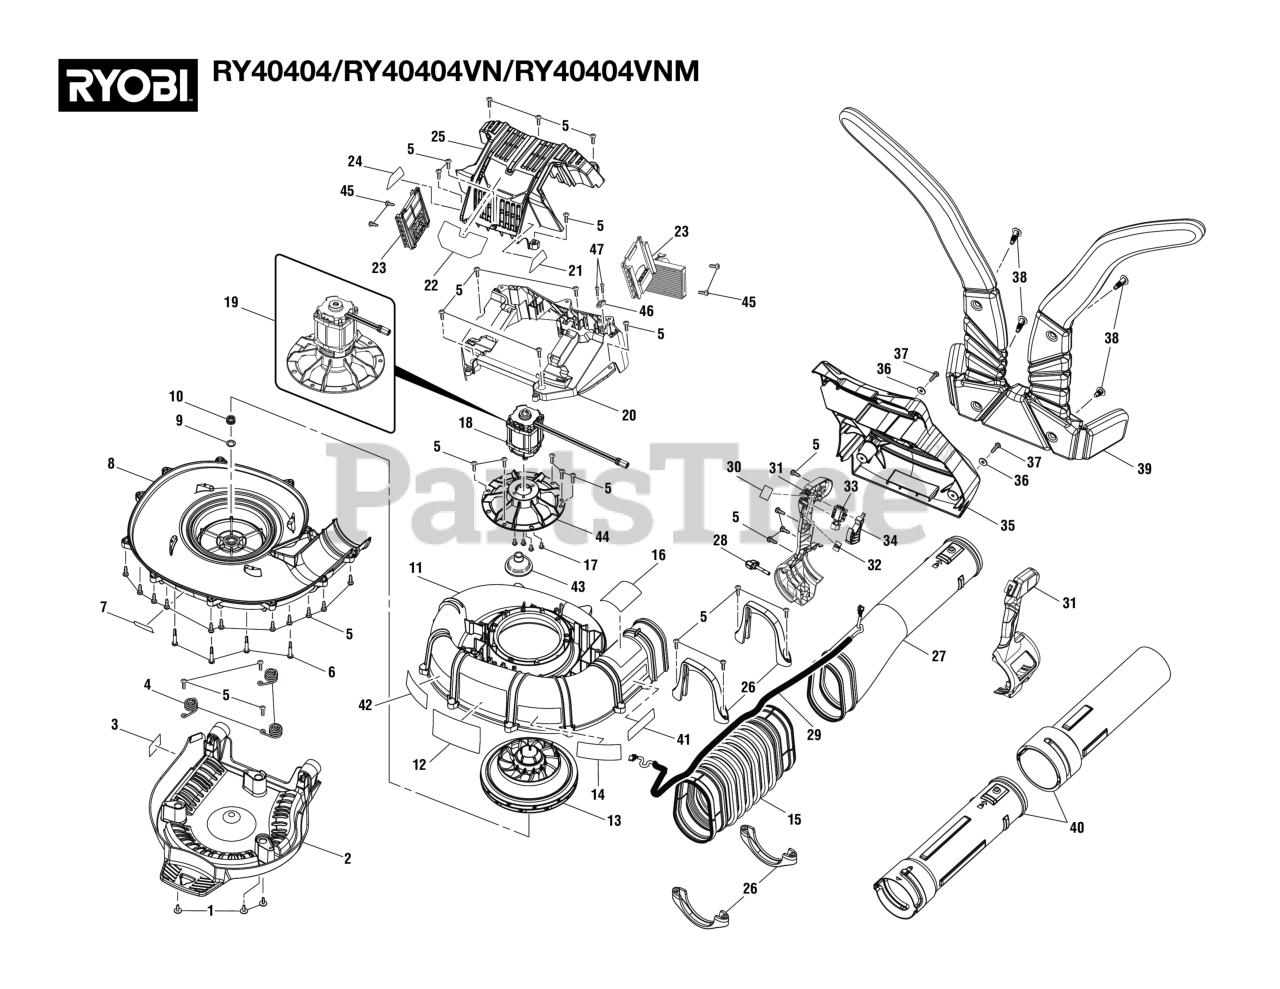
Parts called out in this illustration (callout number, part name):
1	Screw (10-14 x 16 mm)
2	Lower Frame Assembly
3	Data Label
5	Screw (10-14 x 19 mm, T25 Torx Truss Pan Hd. T.F.)
6	Shoulder Screw (M5 x 40 mm, T25 Torx Truss Hd. T.F.)
7	Hair Ingestion Warning Label
8	Outer Volute Assembly
9	Washer (OD18 x ID12.15 x 1.5t)
10	Wavy Spring (ID6.51 x HGT9.52)
11	Inner Volute Assembly
12	Logo Label
13	Fan Assembly
14	MPH Label
15	Bellows Tube
16	Warning Icon Label
17	Screw w/Lock Washer (M5 x 8 mm, Pan Hd.)
18	Motor (40 volt)
19	Motor & Mount Assembly
20	Housing Cover (Bottom)
21	Warning Label (French)
22	40V Lithium Label
23	Motor Controller & Battery
24	Warning Label (Spanish)
25	Housing Cover Assembly
26	Clamp Assembly
27	Handle Blower Tube
28	Blower Knob (1.35 in [34.3 mm])
29	Wire Assembly
30	Turbo Label
31	Throttle Handle & Cruise Control Assembly
32	Turbo Switch
33	Switch Assembly
35	Upper Frame
36	Washer (OD16 x ID6.8 x 1.5t)
37	SCREW (10-14 X 1 in.)
38	Harness Snap Fastener
40	Blower Tube Assembly
41	Battery Warning Label
42	CFM Label
43	Drive Coupler
44	Motor Mount
45	Screw, M4-18 x 12mm, T20 Torx Pan Head
46	Cord Clamp
47	Screw (M4 x 14 mm, T15 Torx Pan Hd.))
